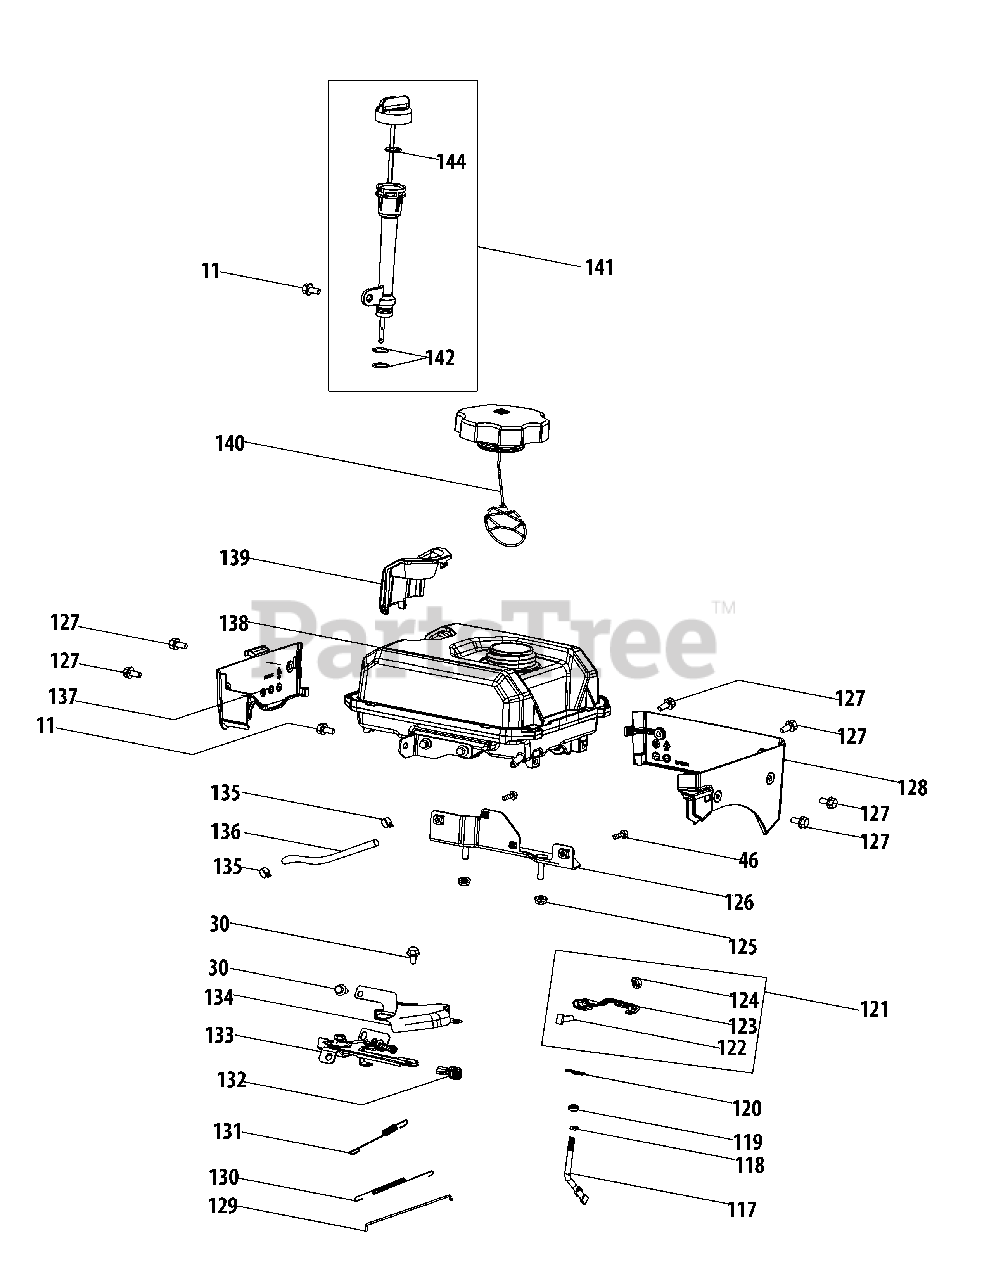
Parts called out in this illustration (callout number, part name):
11	Bolt, M6×12
30	Bolt, M6×12
46	Bolt, M6×18
117	Governor Gear Shaft
118	O-Ring, 5.2×1.9
119	Oil Seal, 6×11×4
120	Cotter Pin
121	Governor Lever
122	Bolt, M6×21
123	Governor Lever
124	Nut, M6
125	Nut, M6
126	Fuel Tank Bracket
127	Bolt, M5×14
128	Decorative Sheet, Left
129	Throttle Linkage
130	Idle Spring
131	Governor Spring
132	Throttle Lever Knob
133	Governor Gear Bracket Assembly
134	Governor Shield
135	Clamp
136	Fuel Hose, 6.3×12.5×162
137	Decorative Sheet, Right
138	Fuel Tank
139	Decorative Cover
140	Fuel Cap
141	Dipstick
142	O-Ring, 15.2×1.5
144	O-Ring, 21×2.77
